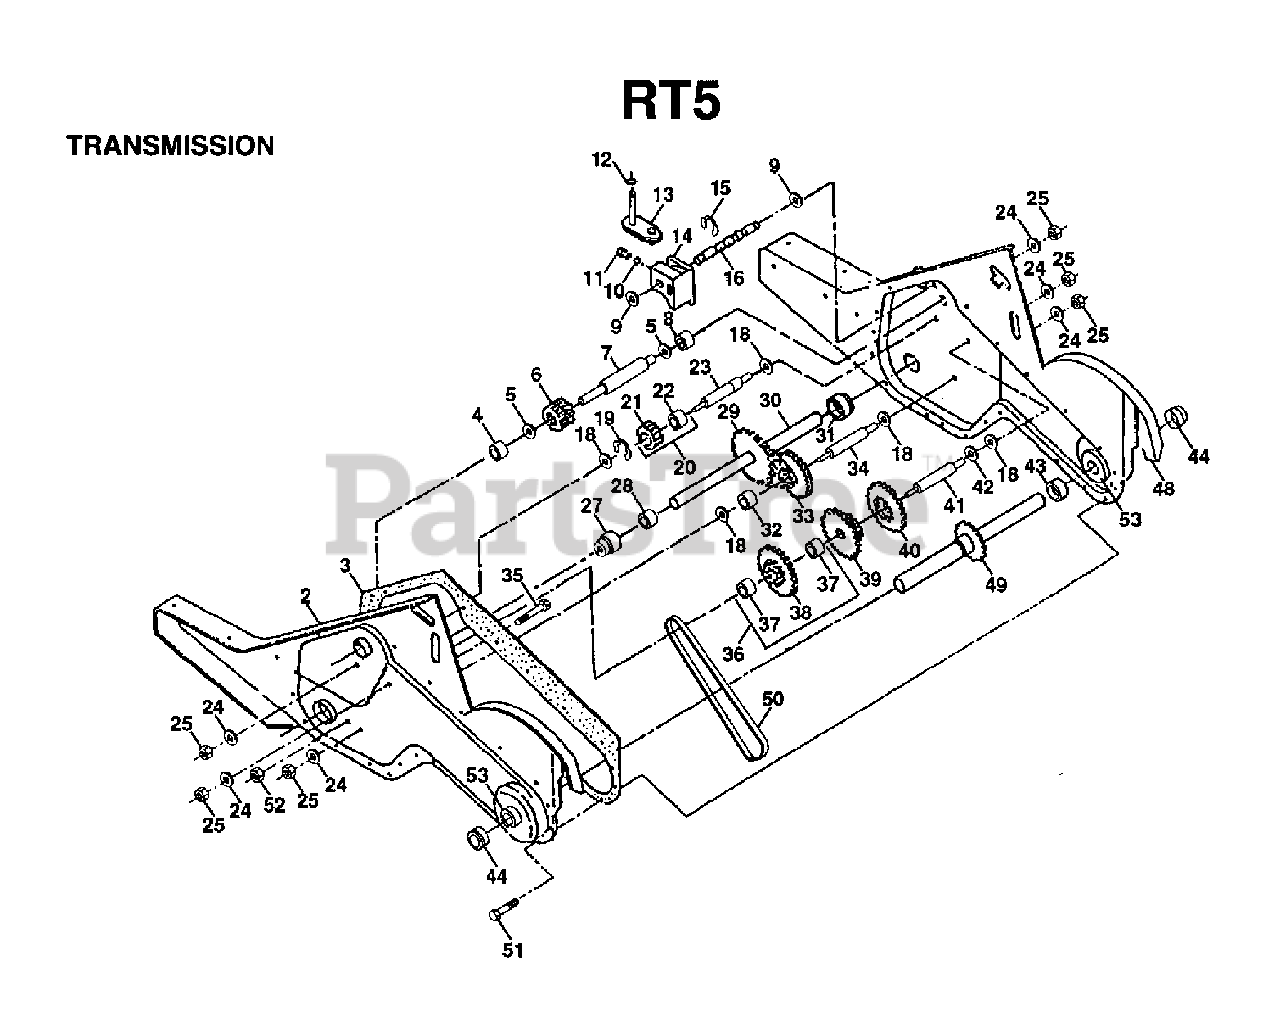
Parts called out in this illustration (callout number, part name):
1	TRANSMISSION ASSY
2	GEARCASE LH W/BRG
3	GASKET TI
4	NEEDLE BRNG LT
5	THRUST WASHER
6	GEAR.PINION.INPUT
7	SHAFT.INPUT."D".TILLER
8	BEARING TI
9	WASHER, SEAL
10	STEEL BALL KIT
11	SPRING-SHIFT CRT
12	O-RING TI
13	SHIFTING ARM
14	SHIFT FORK TI
15	KLIP RING
16	SHAFT.SHIFTER.TILLER
19	KLIP RING
20	GEAR ASSY CRT
21	GEAR-REV IDLR CRT
22	NEEDLE BEARING TI
23	SHAFT CRT
24	LOCKWASHER
27	BEARING, SHAFT LH CRT
29	CHAIN CRT
30	GROUND SHAFT ASS'Y
31	BEARING, SHAFT RH CRT
32	SPACER TI
33	SPRCKT 8 GEAR CRT
34	SHAFT.SECONDARY.REDUCTION.CRT
35	SCRW WHIZ LOK CRT
36	SPROCKET ASS'Y W/BRG
37	BEARING
38	SPROCKET, TINE
39	GEAR TI
41	SHAFT.REDUCTION.TILLER
42	BRNG RACE T
43	SPACER TI
44	SEAL ASM, OIL
48	GEARCASE RH W/BRG
49	TINE SHAFT
50	CHAIN.TILLER
51	SCREW
53	BEARING KIT
